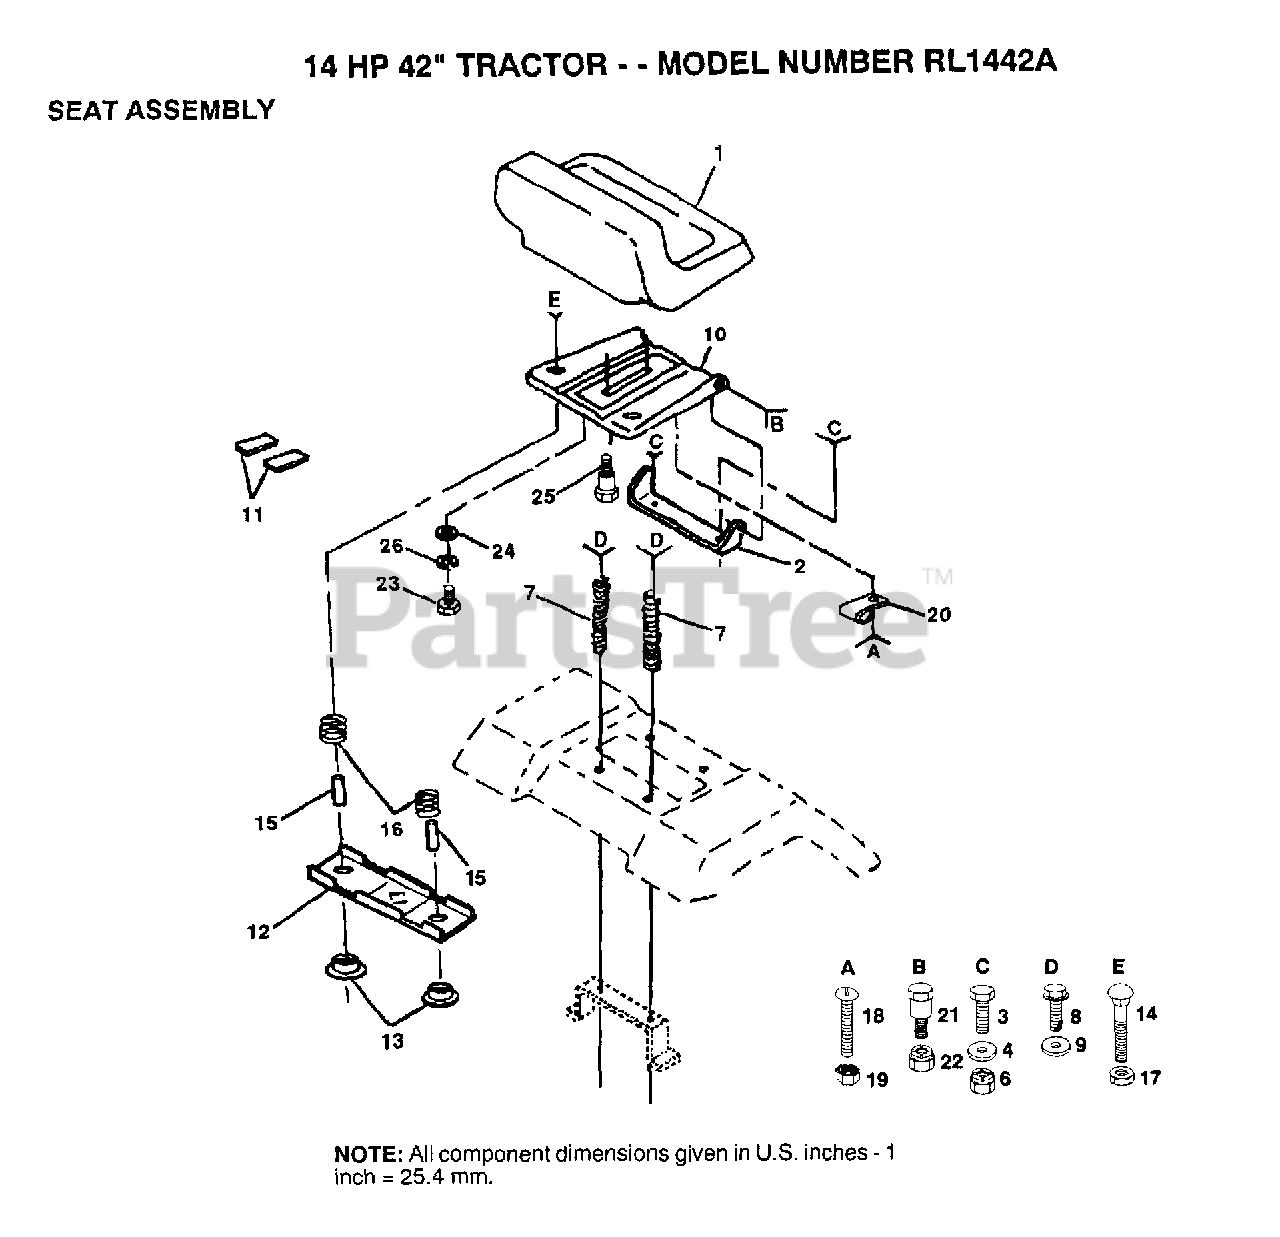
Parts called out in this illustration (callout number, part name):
1	SEAT
4	WASHER
7	SPRING COMPRESSIO
8	SCREW GTV
9	WASHER
11	STRIP FORM
12	BRKT SWITCH
13	BUSHING
15	SPLIT SPACER
16	SPRING
19	"NUT,KEPS"
23	BOLT
24	WASHER
25	"BOLT,SHOULDER"
26	LOCKWASHER
